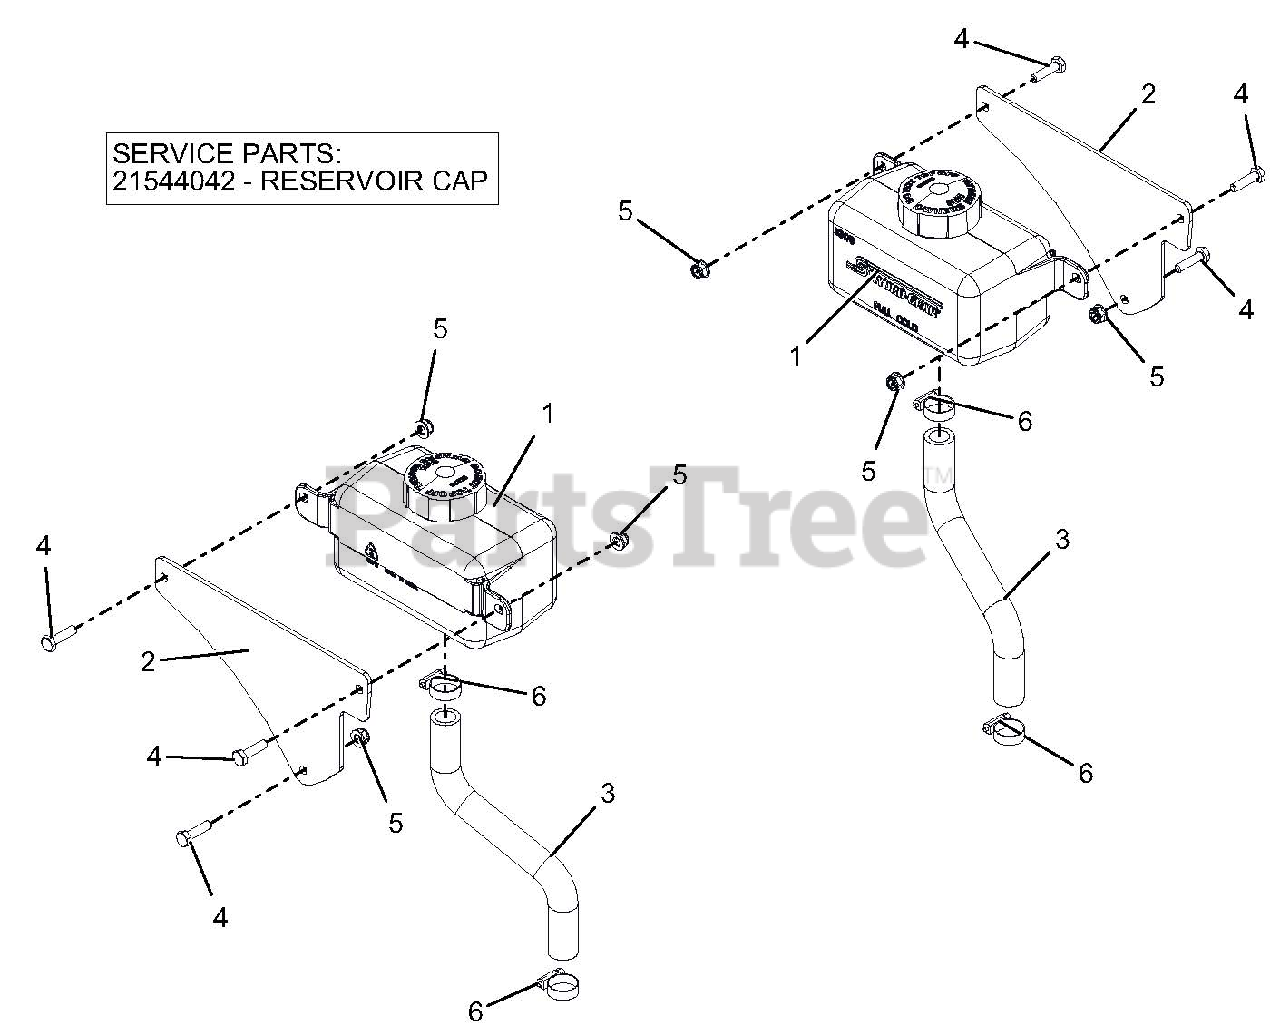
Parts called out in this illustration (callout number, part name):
1	TANK, HYD 1000ML
2	PLATE, HYDRO OVERFLOW TANK MTG
3	HOSE, HYDRO OVERFLOW
4	BLT-HEX .25-20X1.00 GR5 YWZC
5	NUT-LK-NYL-FLG .25-20 YWZC
6	CLAMP, .88 DIA HOSE
7	RESERVOIR CAP
